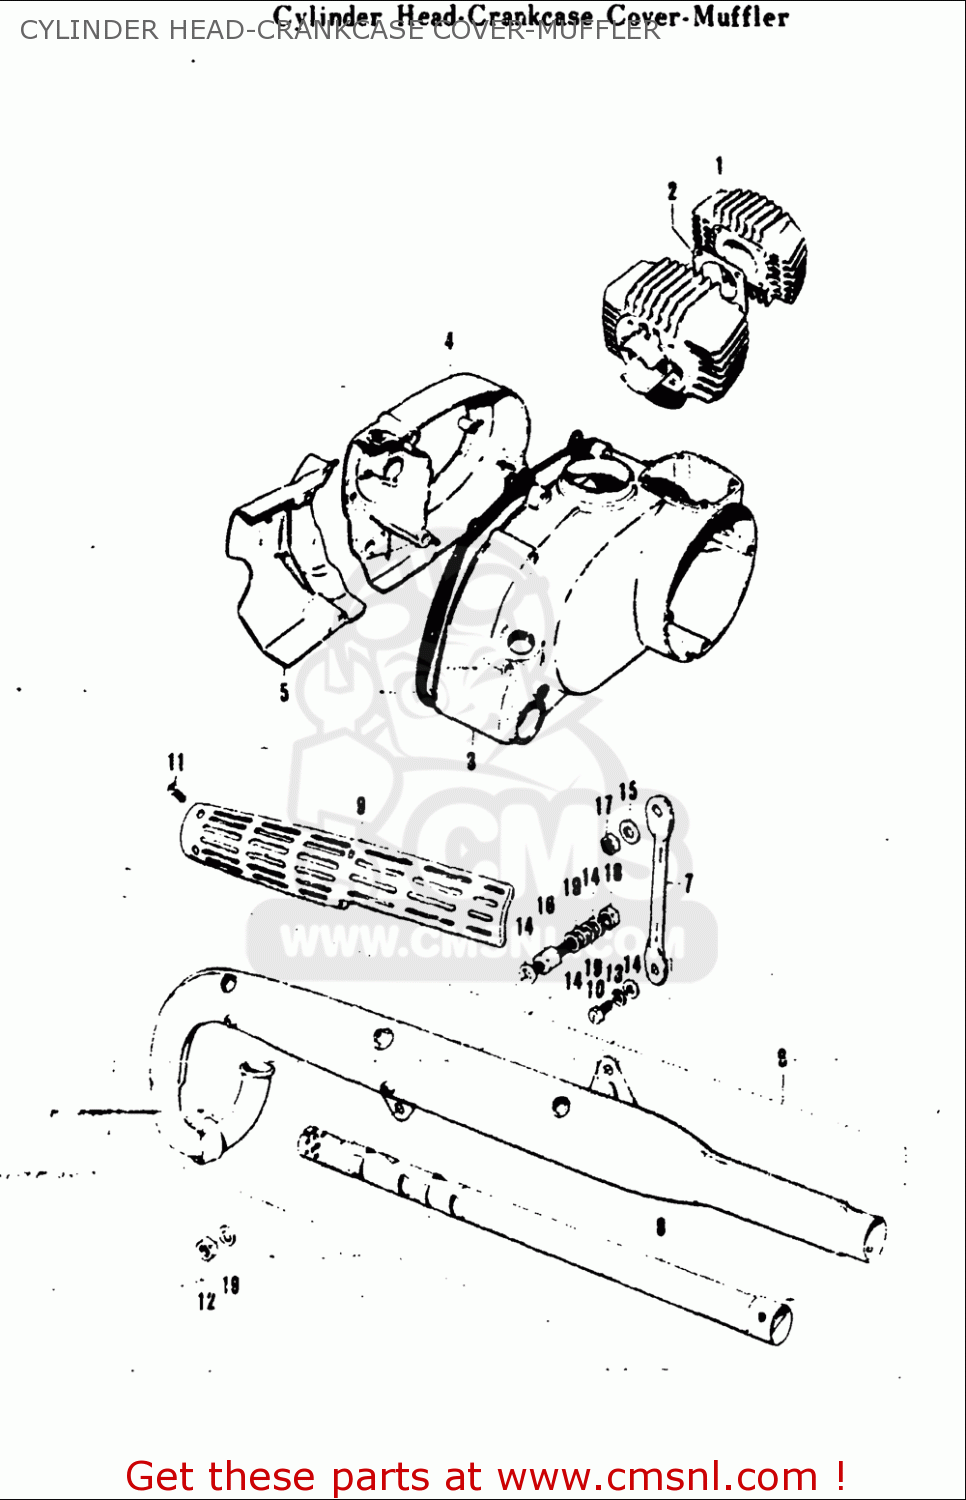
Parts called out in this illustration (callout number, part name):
12	NUT
13	WASHER,LOCK
14	WASHER
15	WASHER
18	NUT
